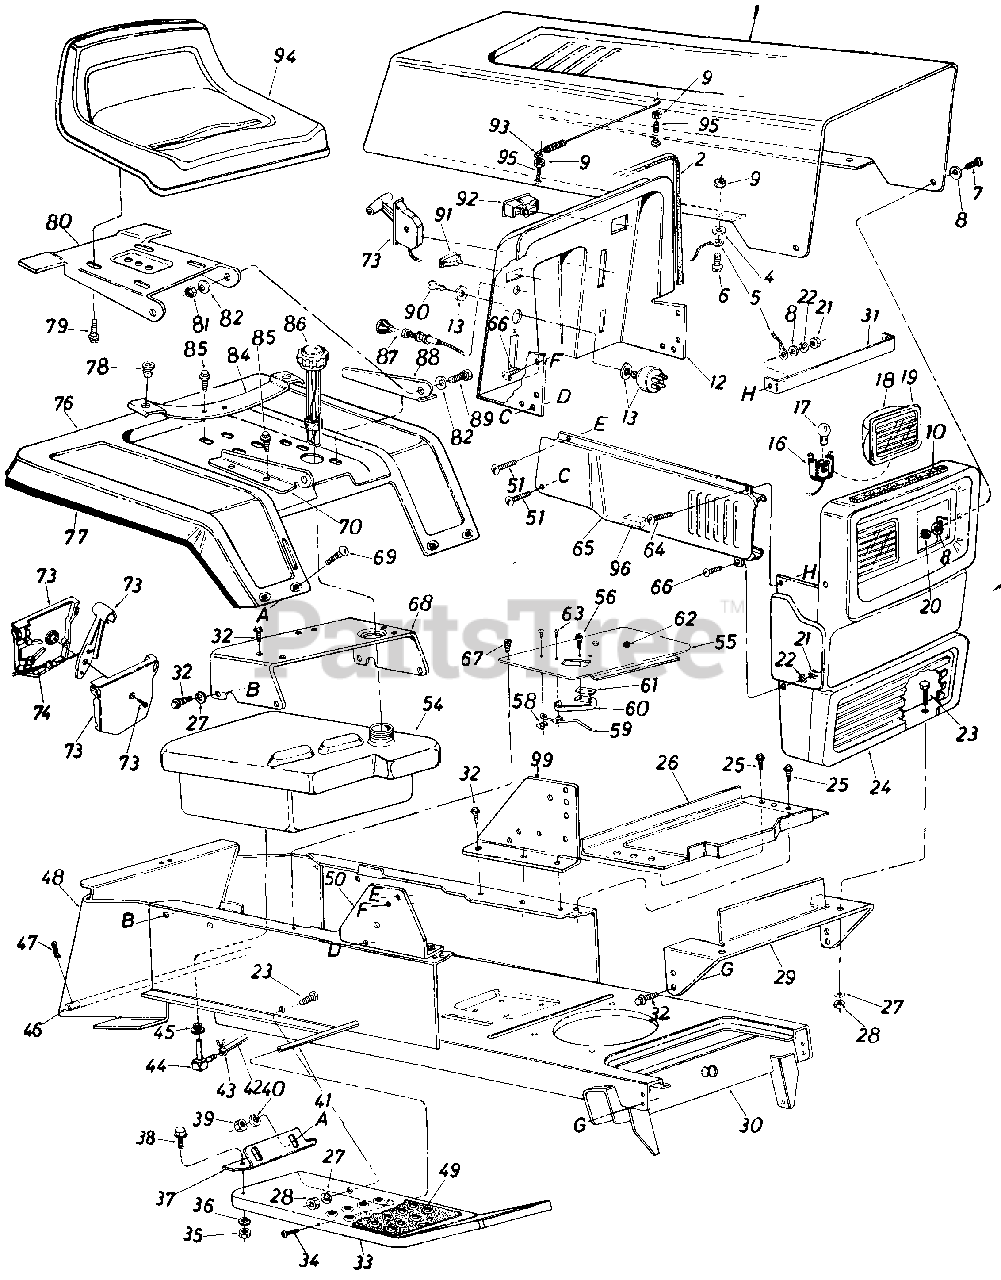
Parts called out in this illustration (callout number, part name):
1	H ood
2	Trim Strip-27" Lg.
4	Fl-Wash. .20" I.D. x .41" O.D.
5	Hood Stop
6	Truss Hd. Mach. Scr. #10-24 x.50" Lg.
7	Hex Bolt 1/4-20 x .62" Lg.
8	Fl-Wash. 1/4" I.D.*
9	Hex Sem Nut #10-24 Thd.*
10	Foam Strip 3/8" x 1" x 14"
12	Dash Ass'y.
13	Ignition Switch
16	Socket
17	Lamp
18	Headlight Housing
19	Lens
20	Hex L-Nut 1/4-20 Thd.
21	Hex Nut 1/4-20 Thd.
22	L-Wash. 1/4" I.D.
23	Hex Bolt 5/16-18 x .75" Lg.
24	Grille
25	Hex Wash. Hd. Scr. 1/4" x .50" Lg.
26	Battery Plate
27	L-Wash. 5/16" I.D.
28	Hex Nut 5/16-18 Thd.
29	Grille Mounting Bracket
30	Lower Frame Ass'y.
31	Tie Strap-Grille/Side Panel
32	Hex Thd. Folling Scr. 5/16-24 x .75" Lg.
33	Running Board-R.H.
34	Truss Mach. Scr. 5/16-18 x .75" Lg.
35	Hex Nut 5/16-18 Thd.*
36	Bell-Wash. .34" I.D. x .87"
39	Hex Nut 1/4-20 Thd.
40	L-Wash. 1/4" I.D.*
41	Running Board Rod
42	Fuel Line 40" Lg.
43	Hose Clamp 3/8"
44	90ø NippIe
45	Bushing
46	Hitch Rod
47	Internal Cotterpin
48	Hitch Plate
49	Foot Pad
50	Dash Support Brkt.-R.H.
51	Hex Wash. Hd Tap Scr. 1/4 x.75" Lg.
54	Fuel Tank
55	Transmission Cover Ass'y.
56	Hex Self-Tap Scr. #8 x .38" Lg.
58	Speed Nut #10-24 U-Type
59	Shift Lever Spring
60	Switch Spring
61	Insulator Plate
62	Snap Bushing
63	Truss Mach. Scr. #10 x .50"
64	Truss Hd. Scr. 1/4-20 x .75"
65	Side Panel-R.H.
66	Truss Mach. Scr. 1/4-20 x .50" Lg.*
67	Truss Mach. "B" Tap Scr. #10 x .50" Lg.
68	Seat Mounting Channel
69	Carriage Bolt 1/4-20 x .50"
70	Seat Bracket-R.H.
73	Throttle Control Box Ass'y.
74	Throttle Control Wire
78	Grommet
79	Hex Wash. Hd. AB-Tap Scr. 3/8 x .75" Lg.
80	Seat Pivot Bracket
81	Hex Cent. L-Nut 5/16-18 Thd.
82	Belleville Wash. .34" I.D. x .88" O.D.
84	Seat Spring
85	Hex Wash. Hd. Self-Tap Scr. 5/16-18 x .50" Lg.
86	Gas Cap w/Gauge
87	Choke Control Comp.
88	Seat Bracket-L.H.
89	Hex Bolt 5/16-18 x .75" Lg.
90	Ignition Key
91	Light Switch
92	Ammeter
93	Hood Spring
94	Seat Ass'y.
95	Hex Screw #10-24 x 1.0" Lg.
96	Rubber Strip 1/2" Sq. x 2-1/2" Lg.
99	Dash Support Brkt.-L.H.
